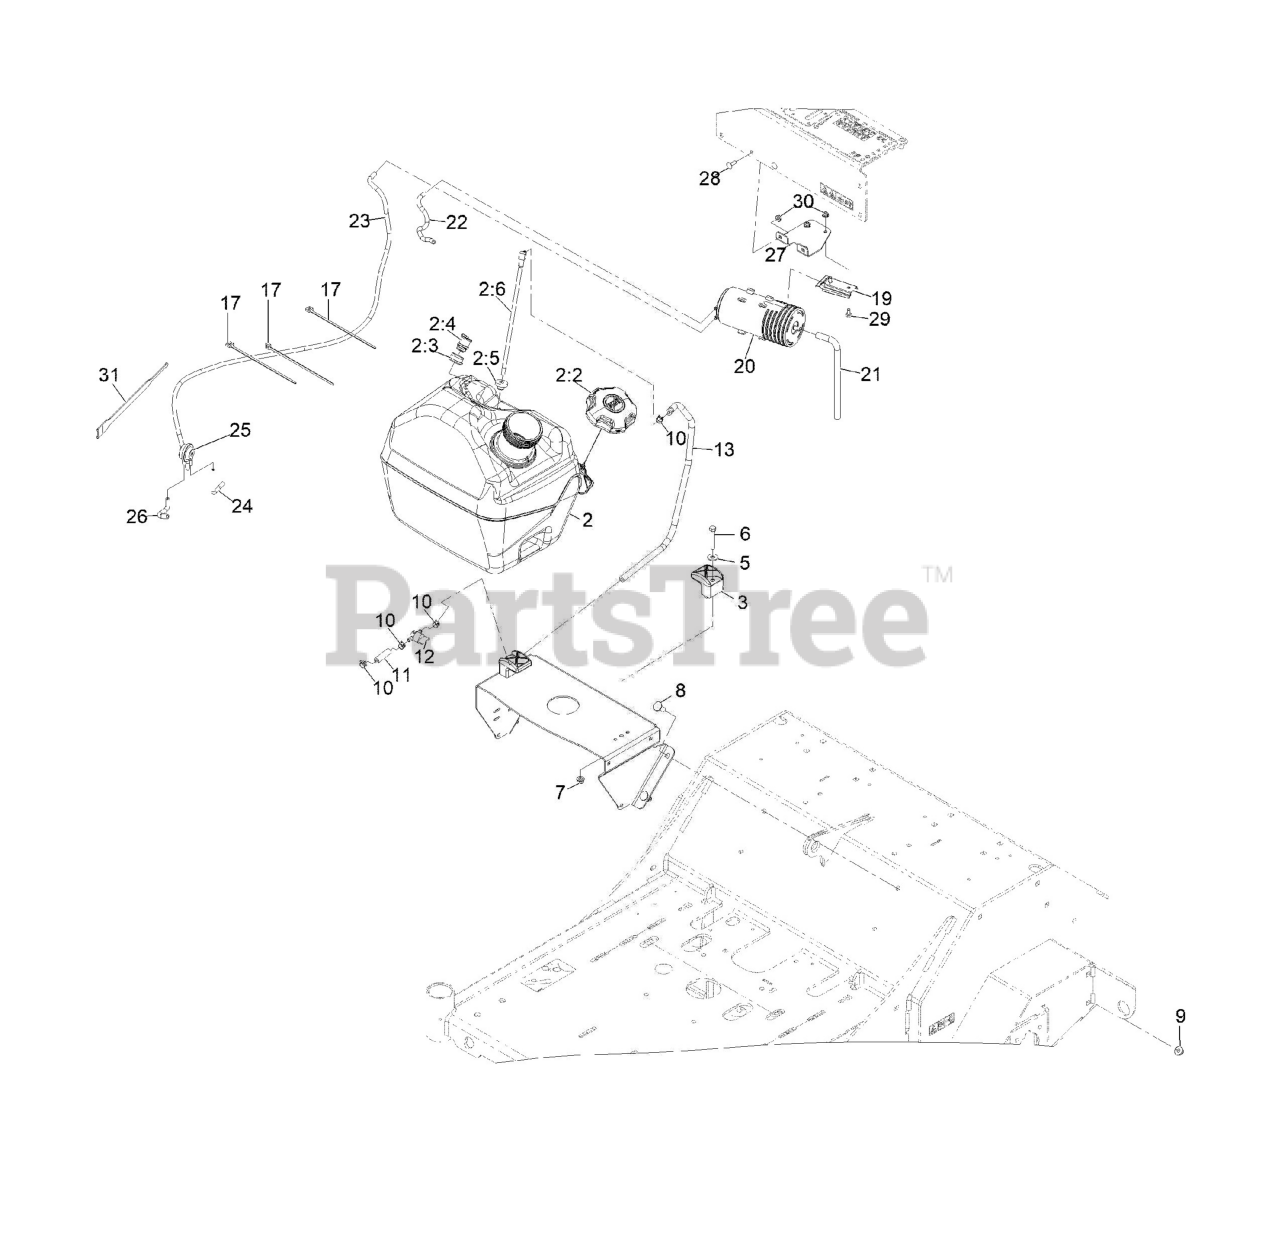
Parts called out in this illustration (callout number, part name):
2	Fuel Tank ASM, 5 Gal
2:2	CAP-FUEL, RATCHETING
2:3	GROMMET
2:4	VALVE-VENT, FUEL
2:5	BUSHING
2:6	FITTING, FUEL W/LINE AND SCREEN
5	WASHER-FLAT
6	SCREW-HH
7	NUT-HF, NI
8	SCREW-CARR
9	NUT-HF, NI
10	CLAMP-HOSE
11	HOSE-FUEL
12	VALVE-FUEL
13	HOSE-LINE, GAS
17	TIE-CABLE
19	BRACKET-CANISTER, CARBON
20	CANISTER-CARBON, 800CC
21	HOSE-VENT, CANISTER
22	HOSE-EMISSIONS
23	HOSE-VENT, FORMED
24	HOSE-VENT, FORMED
25	VALVE-CONTROL, VACUUM
26	HOSE-VENT, FORMED
27	BRACKET-MOUNTING, CANISTE
28	BOLT-CARR
29	SCREW-HH
31	STRAP-VELCRO, CABLE TIE
